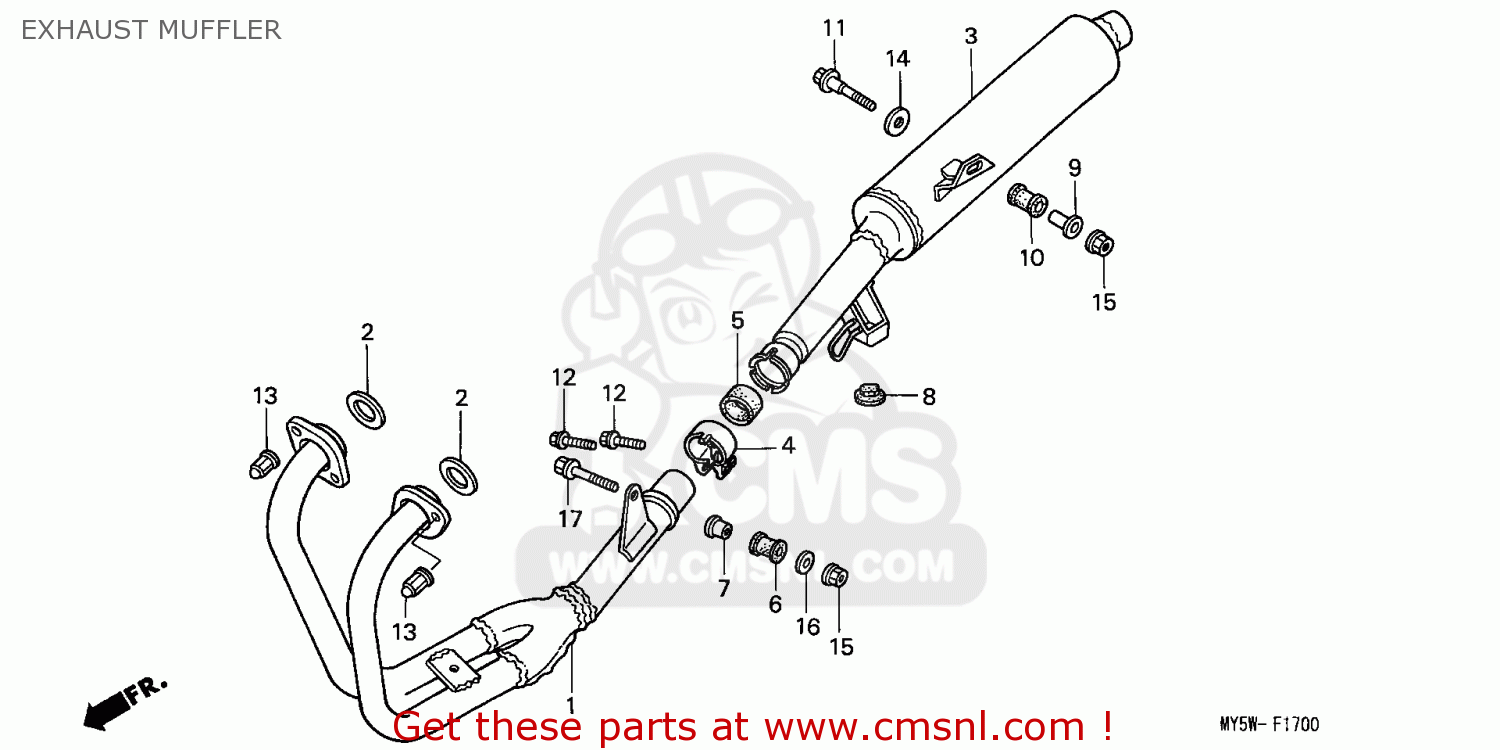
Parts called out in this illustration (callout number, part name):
1	PIPE COMP.,EXH.
2	GASKET,EX.PIPE (NAS)
3	MUFFLER COMP..
4	BAND,MUFFLER
5	PACKING,MUFFER (NAS)
6	RUB,MUF.MOUNTING
7	COLLAR,MUFFLER MO
8	RUBBER,RR.COWL ST
9	COLLAR,MOUNT RUB.
10	RUBBER,MUFFLER MO
11	BOLT,FLANGE,8X50
12	BOLT,FLANGE,8X35
13	NUT,CAP,6MM
14	WASHER 8.3MM
16	WASHER,PLAIN, 8MM
17	BOLT,FLANGE,8X45
